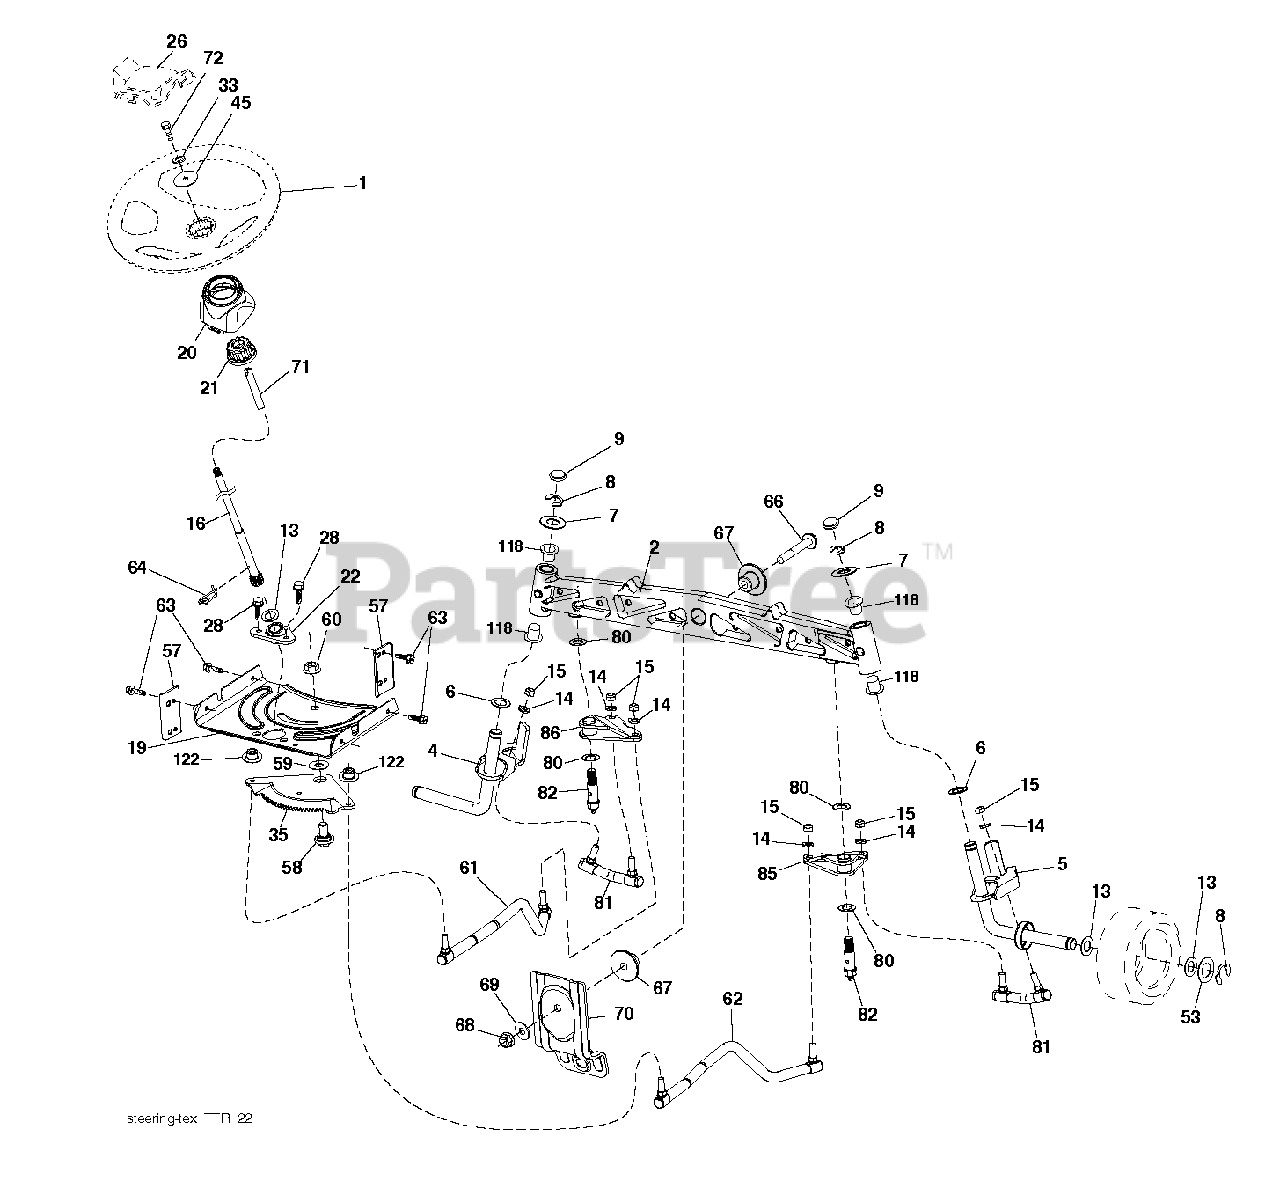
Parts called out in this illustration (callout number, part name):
1	WHEEL.STEER.HUSQ.SR.498.OVMLD
2	RP SUBASM.AXLE.CAST.NZTR.
4	SPINDLE WELDMENT.SPINDLE.LH.15
5	SPINDLE WELDMENT.SPINDLE.RH.15
6	THRUST WASHER
9	CAP.SPINDLE.BLACK
14	WASHER, LOCK 3/8
15	NUT CROWNLOCK 3/8-24
16	SHAFT SHAFT.STEERING/HIGH3PLAT
19	PLATE.STEER.DDL.NLT/NG
20	STEERING.BOOT.HUSQ.LT
21	RP STEERING.WHEEL.ADAPTER
22	BUSHING.ASM.STEERING.A
26	INSERT.CAP.WHL.STRG.HUSQ.PREM
28	SCREW, 3/8-16X3/4
33	LOCKWASHER
35	GEAR GEAR.SECTOR.TEX.NZTR
45	WASHER.11/32
53	WASHER.HARDENED
57	BRACKET.UPSTOP.TEX
58	BOLT.SHOULDER.SECTOR.P
59	WASHER.THURST.SECTOR.S
60	NUT FLANGE LOCK 5/8-11
61	LINK SUBASM.LINK.DRAG.LH.NZTR
62	TUBE TUBE
63	SCREW
64	RETAINER.CLIP.SPRING.S
66	BOLT HEX FGHD 7/16-14 X 3 SERR
67	BUSHING.PM.FRONT AXLE
68	NUT.LOCK.FLANGE.7/16
69	WASHER.1.5X.505X.118
70	BRKT.DECK.SUSPENSION.F
71	SHAFT.EXTEN.STRG.SPLINE
72	BOLT 5/16-18 X 4 W/PATCH
80	THRUST WASHER
81	LINK SUBASM.LINK.CROSS.NZTR
85	PIVOT SUBASM.PIVOT.RH.NZTR
86	PIVOT SUBASM.PIVOT.LH.NZTR
118	BUSHING, AXLE CAST
122	CAP.GEAR.SECTOR.TEX
